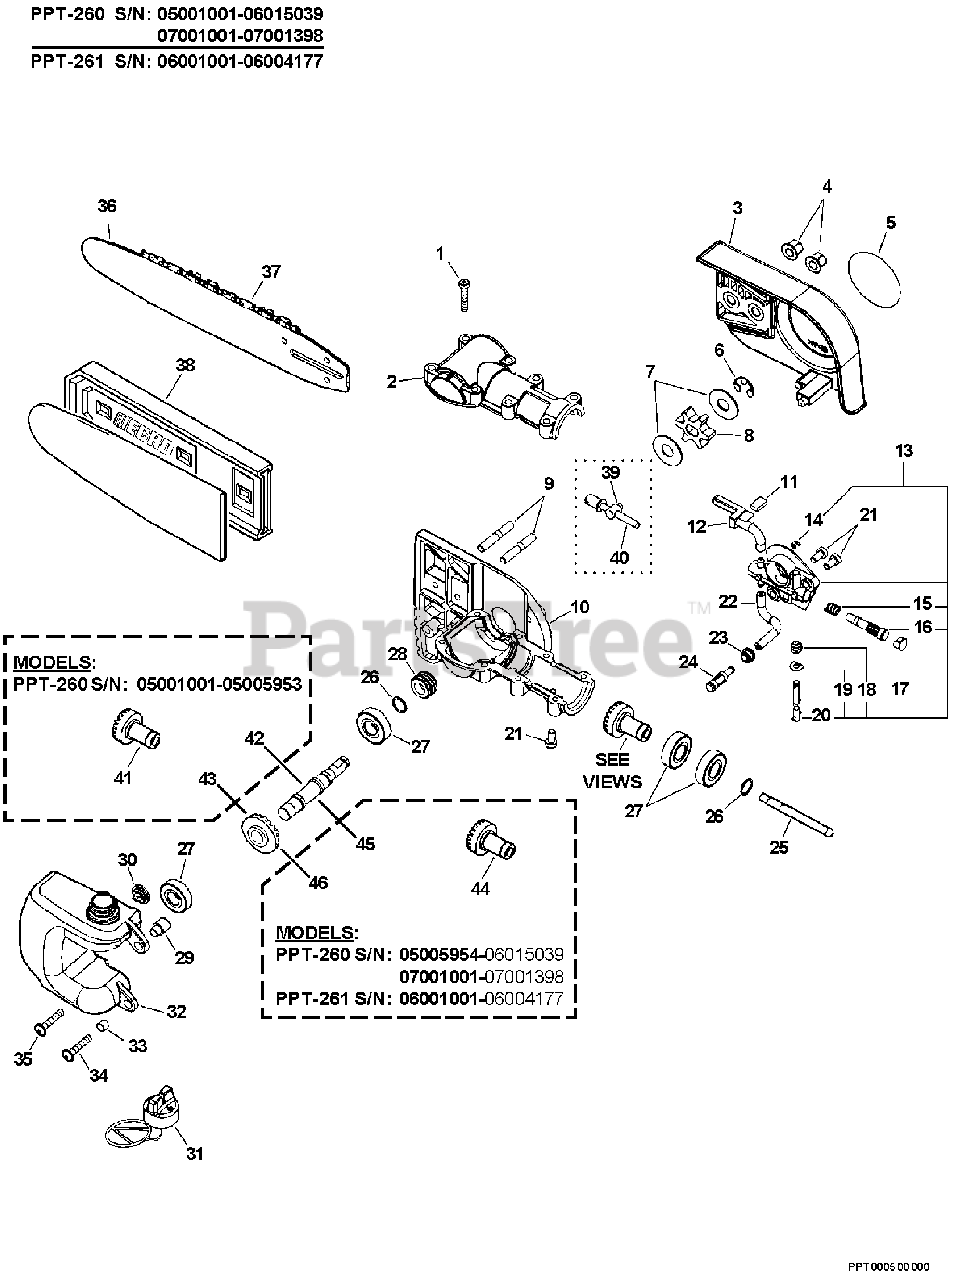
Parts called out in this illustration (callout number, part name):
1	SCREW - 5X25
2	CASE, GEAR - UPPER
3	GUARD, SPROCKET
4	NUT - 6 -- FLANGE
5	LABEL - ECHO
6	RING, RETAINING
8	SPROCKET, DRIVE
9	STUD - 6
10	CASE, GEAR - LOWER
11	PAD, FOAM
12	PIPE, OIL OUTLET
13	AUTO-OILER ASSY
14	RING, RETAINING
15	SPRING, PLUNGER
16	PLUNGER ASSY
17	CAP, OIL PUMP
20	NEEDLE, ADJUST
21	SCREW - 5X10
22	PIPE - 3X6X75 -- BLACK
23	GROMMET
24	FILTER, OIL
25	CONNECTOR, SHAFT
26	RING, RETAINING - 12
27	BEARING, BALL - 6001
28	GEAR - WORM
31	CAP ASSY
32	TANK, OIL
34	SCREW - 5X16
35	SCREW - 5X20
36	GUIDE BAR - 12" (30cm) Intenz
37	SAW CHAIN - 12" (30cm)
38	COVER, GUIDE BAR - 12" (30cm)
39	TENSIONER, CHAIN
40	SCREW, TENSIONER
41	GEAR - BEVEL
42	GEAR - SHAFT
43	GEAR - BEVEL
44	GEAR - BEVEL
45	GEAR - SHAFT
46	GEAR - BEVEL
